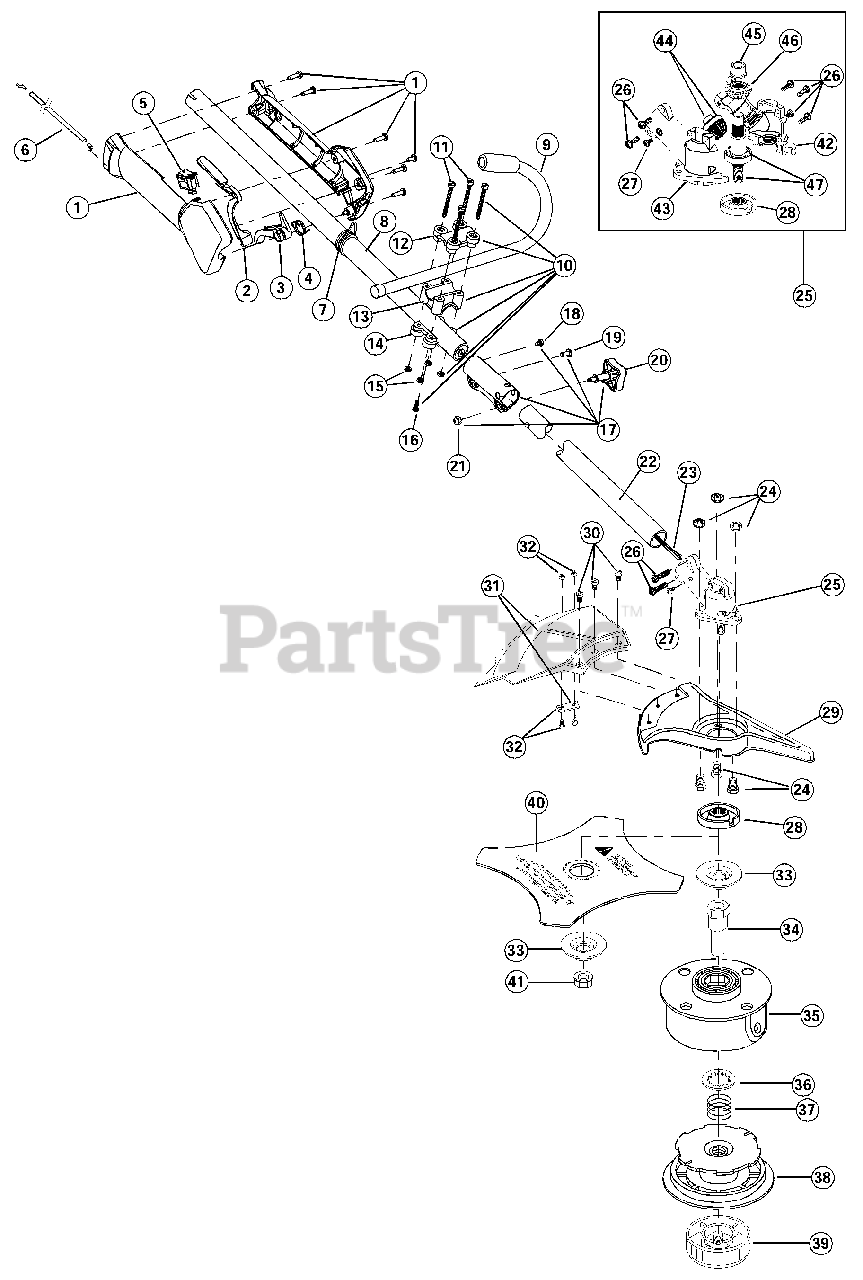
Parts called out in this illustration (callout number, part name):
1	Throttle Housing & Trigger Assembly
2	Throttle Trigger Lock-Out
3	Throttle Trigger
4	Throttle Trigger Spring
5	Switch Assembly
6	Throttle Cable Assembly
7	Harness Clip
8	Upper Drive Shaft Housing Assembly
9	J-Handle Assembly
10	Handle Bracket Assembly
12	Upper Handle Clamp
13	Middle Handle Clamp
14	Lower Handle Clamp
16	Anti-Rotation Screw
17	Click-Link Coupler
20	Adjustment Knob
21	Knob Retaining Nut
22	Lower Drive Shaft Housing Assembly
23	Lower Flexible Drive Shaft
24	Shield Mount Screw Assembly
25	2 piece Gearbox Assembly
26	Gearbox Mounting Hardware
27	Anti-Rotation Screws
28	Blade Driver
29	Blade Shield/Shield Mount
30	Shield Mounting Screw
31	Shield and Blade Assembly
32	Blade Assembly
33	Retaining Washer
34	Spool Shaft
35	Outer Spool and Eyelet Assembly
36	Retainer
37	Spring
38	Inner Reel
39	Bump Head Knob Assembly
40	4-Tooth Blade
41	Nut
42	Left Housing
43	Right Housing
44	Pinion Gear Assembly
45	Output Shaft Bushing
46	Output Shaft Gear
47	Output Shaft Assembly
